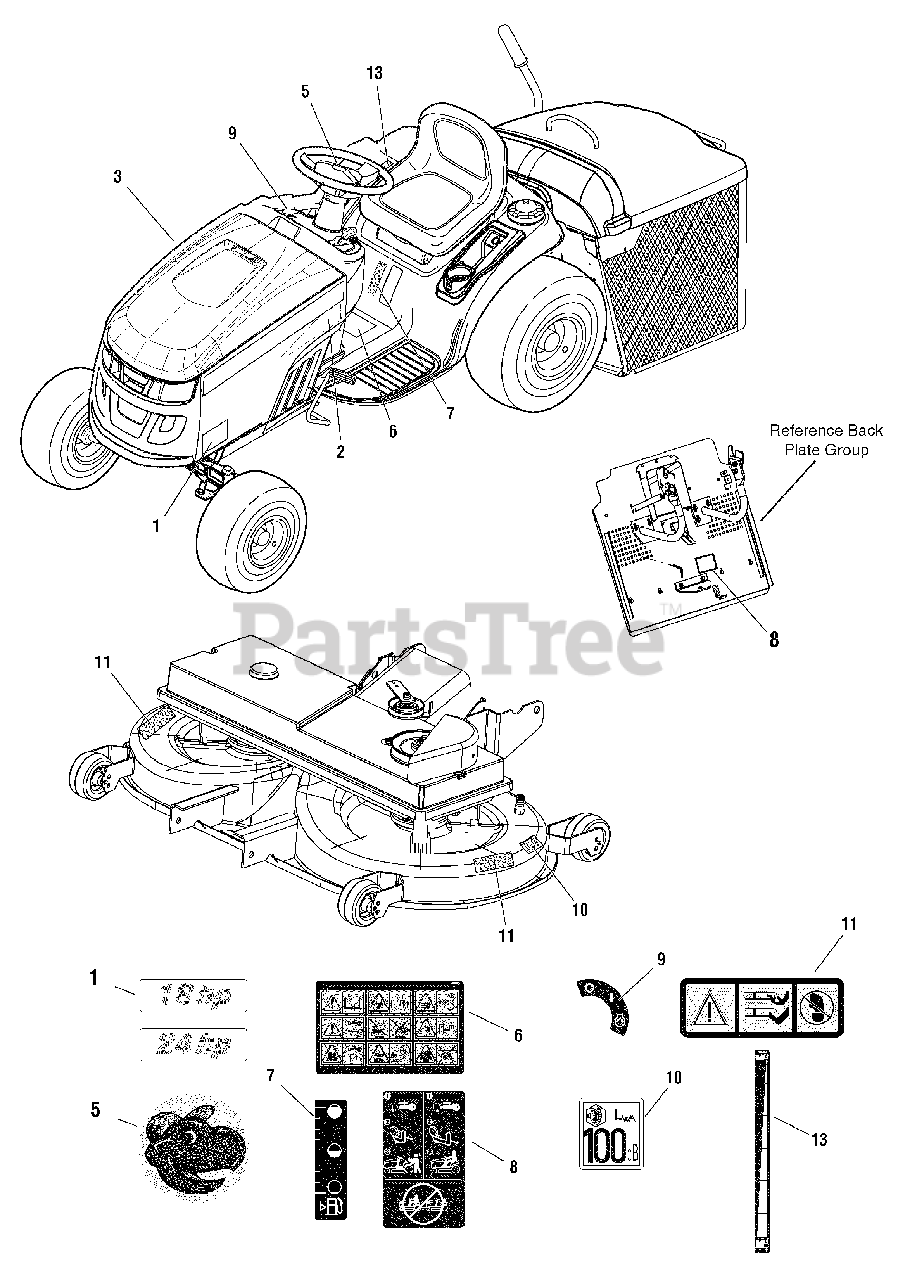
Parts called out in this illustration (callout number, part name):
1	DECAL, 18HP
1	DECAL, 24HP
2	DECAL, Snapper LH Stripe
3	DECAL, Snapper RH Stripe
5	DECAL, Snapper Steering Wheel
6	DECAL, Tunnel
7	DECAL, Fuel level
8	DECAL, Trans/Tow Release Lever
9	DECAL, Ignition Switch White/Blk
10	DECAL, Noise
11	DECAL, Safety
13	DECAL, Mower Height
